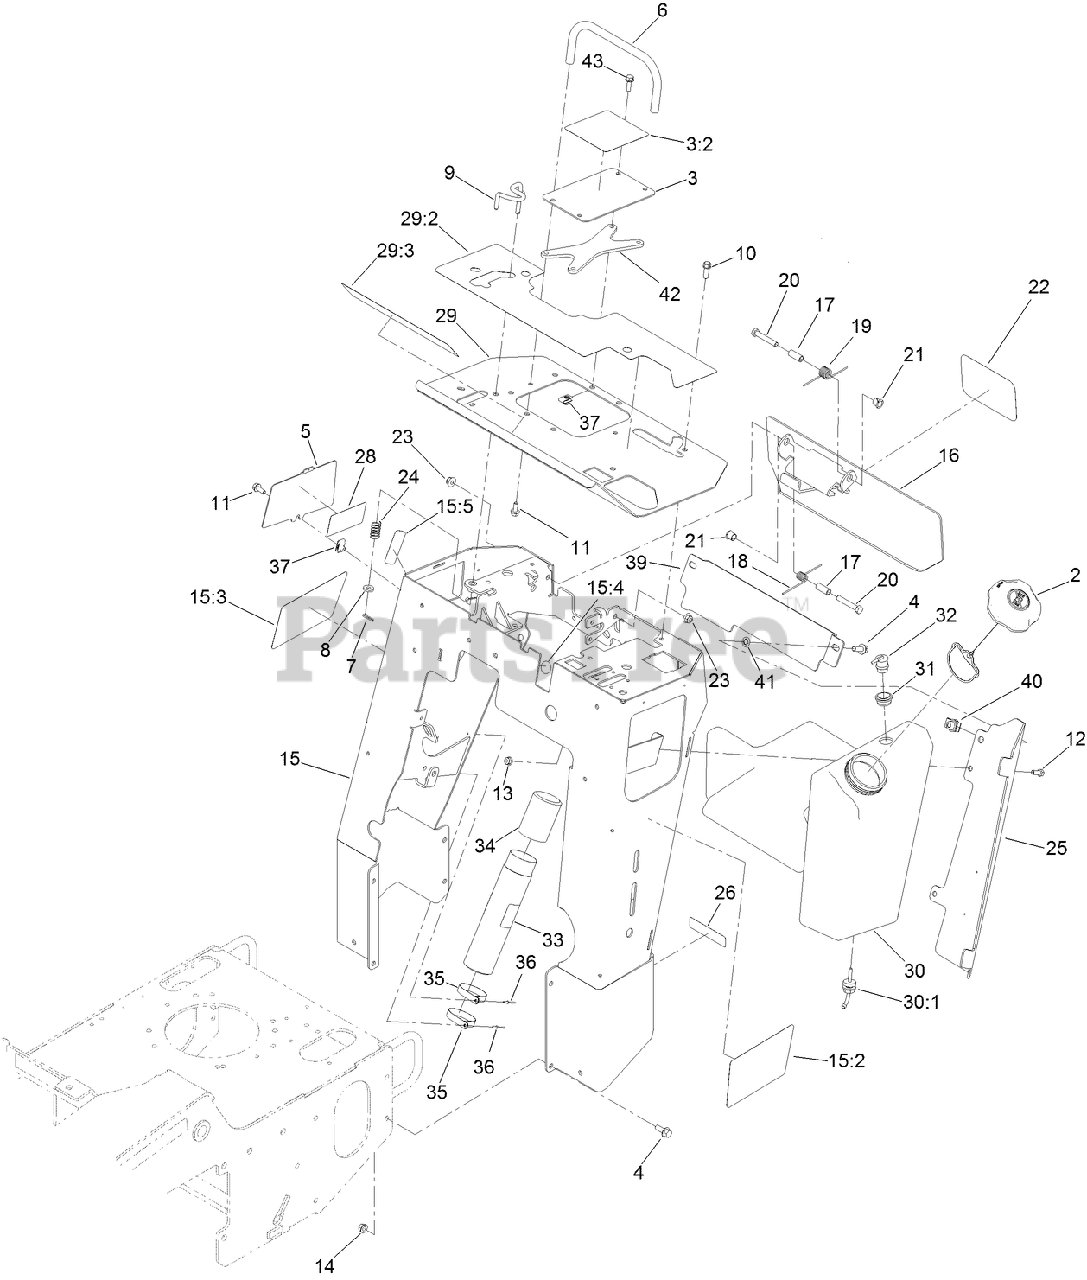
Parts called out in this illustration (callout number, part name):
2	CAP-FUEL, RATCHETING
3	COVER-HANDLE, TRACTION
3:2	DECAL-TRACTION
4	SCREW-HHF
5	PLATE-COVER, ACCESS
6	BAR-REFERENCE
8	WASHER-FLAT
9	ROD-INTERLOCK
10	SCREW-TAPTITE
11	SCREW-HHF
12	SCREW-HH
13	NUT-HF, NI
14	NUT-FLANGE
15	CONTROL TOWER ASM
15:2	DECAL-SIDE, LH
15:3	DECAL-SIDE, RH
15:4	DECAL-PARKING BRAKE
15:5	DECAL-BRAKE, PARKING
16	PLATE-REVERSE
17	SPACER-SPRING
18	SPRING-TORSION, LH
19	SPRING-TORSION
20	SCREW-HH
21	BUSHING-NYLINER
23	NUT-HF, NI
24	SPRING-CONTROL
25	BRACKET-COVER, TANK
26	DECAL-ARRESTOR, SPARK
28	DECAL-FUSE
29	COVER-CONTROL
29:2	DECAL-PANEL, CONTROL
29:3	DECAL-SAFETY
30	TANK-FUEL
30:1	FITTING-FUEL, BULKHEAD
31	GROMMET
32	VALVE-VENT, FUEL
33	TUBE-MANUAL
34	CAP-HOUSING
35	CLAMP-R
36	RIVET-POP
37	NUT-U
39	GUARD-TOWER
40	NUT-TINNERMAN
41	NUT-PUSH
42	SPACER-COVER
43	SCREW-HHF
